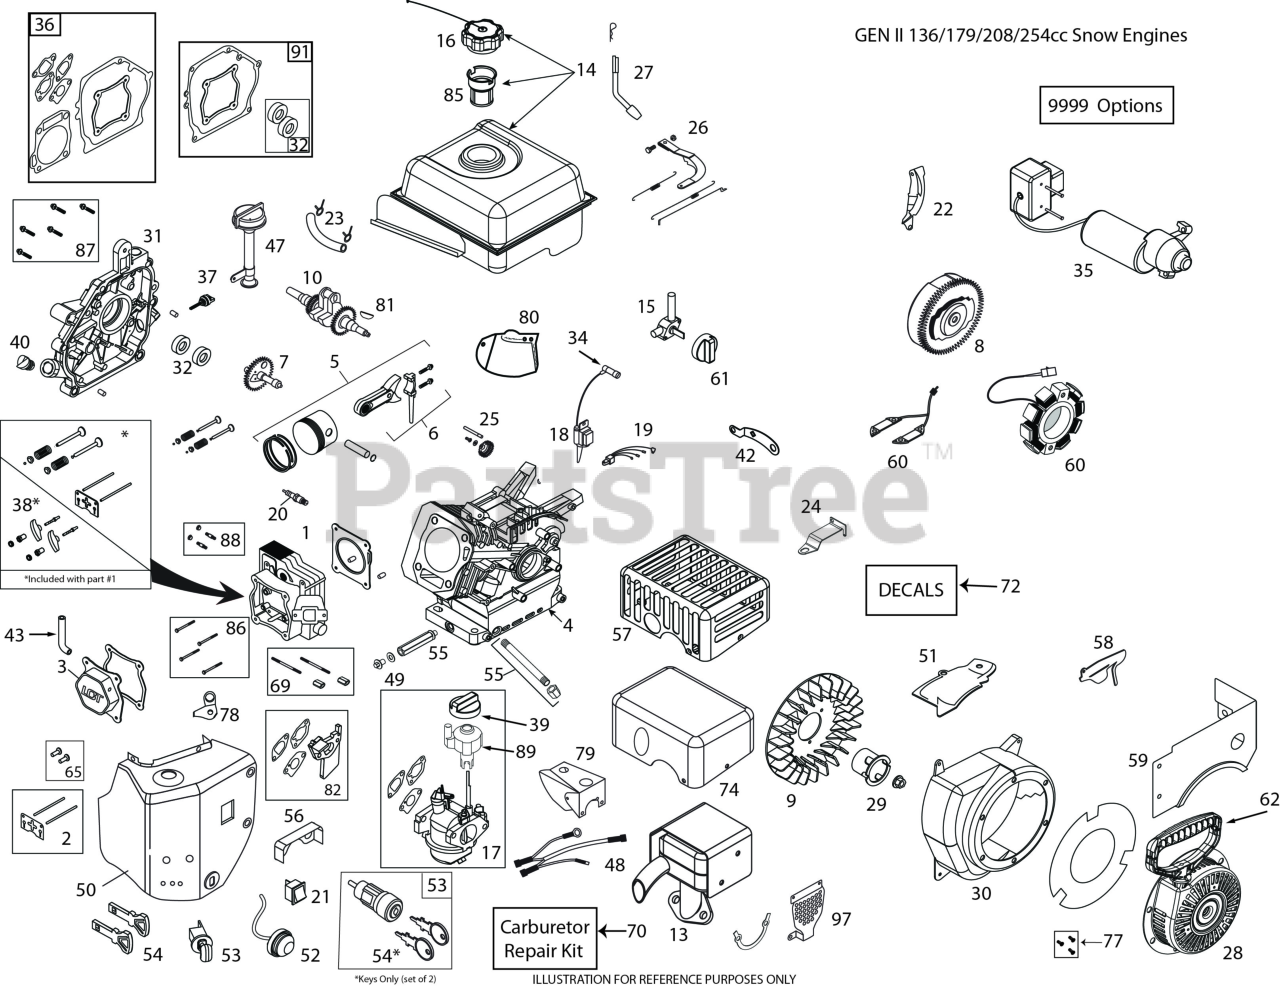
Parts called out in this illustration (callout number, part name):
1	CYLINDER HEAD ASSY (W/GASKET)
2	PUSH ROD & PLATE KIT (W/GASKT)
3	VALVE COVER (W/GASKET)
5	PISTON & ROD ASSEMBLY
6	CONNECTING ROD ASSEMBLY
7	CAMSHAFT - MCR
8	FLYWHEEL - ELECTRIC START
9	COOLING FAN - FLYWHEEL
10	CRANKSHAFT (#18 KEYED)
13	MUFFLER ASSEMBLY
14	FUEL TANK ASSY
15	FUEL TANK ON/OFF VALVE
16	CAP, FUEL TANK (BLACK)
17	CARBURETOR (W/GASKETS)
18	IGNITION COIL (CDI) (STANDARD)
19	CDI MODULE - BLACK BOX
20	SPARK PLUG, ARIENS AX
21	ON/OFF SWITCH - ROCKER (RED)
24	SPEED CONTROL BRACKET (FIXED)
25	GOVERNOR GEAR ASSEMBLY
26	GOVERNOR ARM & LNK KIT 3600RPM
27	GOVERNOR ARM PADDLE
28	RECOIL STARTER ASSY RND-BLACK
29	STARTER CUP HEX STYLE STARTER
30	BLOWER HOUSING (W/WELDNUT)
30	BLOWER HSG W/INTEGRATED BAFFLE
31	CRANKCASE COVER ASSY W/GASKET
31	CRANKCASE COVER-HIGH, PRESS IN
32	OIL SEAL KIT(2 PCS 3/4" CRANK)
34	SPARK PLUG BOOT (W/MTL SHIELD)
35	120V ELECTRIC STARTER
36	ENGINE GASKET KIT
37	SMALL BLACK OIL DIPSTICK
38	ROCKER ARM KIT (W/GASKET)
39	CHOKE CONTROL KNOB (RED)
40	NON-REMOVABLE PLASTIC PLUG
43	BREATHER TUBE
47	HIGH OIL-FILL TUBE/DIPSTICK
48	WIRE HARNESS
49	OIL DRAIN PLUG (W/WASHER)
50	HEATER BOX KIT
51	SHIELD - CYLINDER
52	PRIMER BULB WITH HOSE-SNOW (RED)
53	SAFETY KEY SWITCH (W/KEYS) (RED)
54	KEY, PUSH/PULL LCT (2/PACKAGE)
55	OIL DRAIN TUBE
56	CARBURETOR VAPOR SHIELD
58	SHIELD - GOVERNOR LINKAGE
59	FUEL TANK SKIRT
61	FUEL CONTROL KNOB (RED)
62	STARTER GRIP-SNOW (DELUXE)
65	TAPPET KIT (SET OF 2)
69	CARBURETOR STUDS & COUPLNG KIT
70	CARBURETOR REPAIR KIT
72	Stormforce Label Kit
74	MUFFLER HEAT SHIELD COVER
77	RECOIL BOLT KIT
78	BREATHER TUBE BRACKET
79	CARBURETOR COVER
80	TOP SHIELD
81	WOODRUFF FLYWHEEL KEY 5-PACK
82	CARBURETOR SPACER
85	FUEL TANK STRAINER
86	HEAD BLT KIT 136-179-208-254CC
87	CC COVER BLT KIT 179-208-254CC
88	MUFFLER MTG STUD KIT
91	CRANKCASE GASKET KIT 208GEN1&2
97	MUFFLER MANIFOLD SHIELD
9999	HIGH ALT JET-208CC L10-1 CARB
9999	HARDWARE KIT (4 M6X10 FLG BLT)
9999	OIL, ARIENS 5W30 32 OUNCE, SYNTHETIC BLEND
